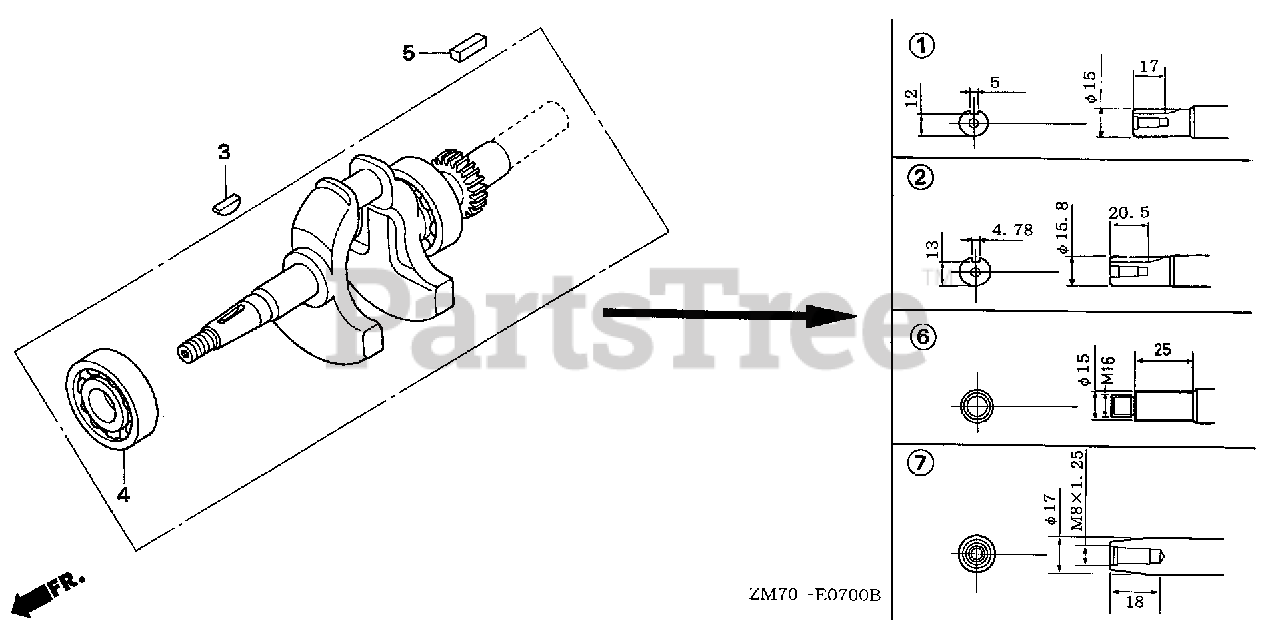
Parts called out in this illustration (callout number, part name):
2	CRANKSHAFT
3	KEY, SPECIAL
4	BEARING, RADIAL BALL (6203)
5	KEY (4.78MM)
